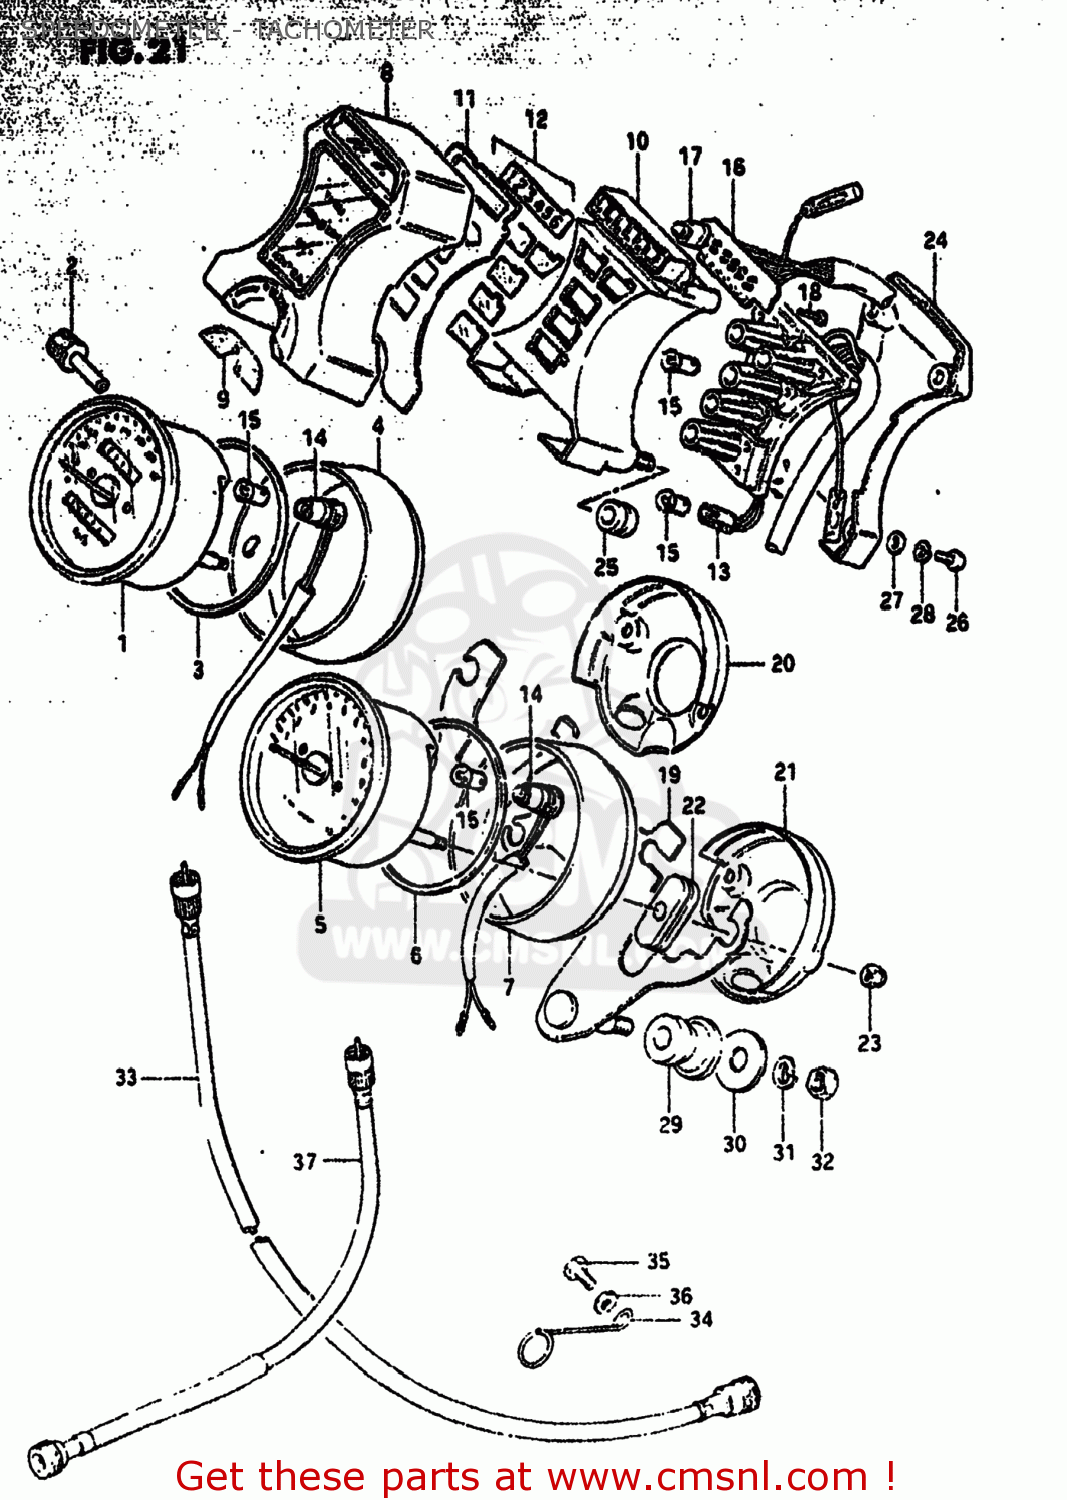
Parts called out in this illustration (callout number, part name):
1	SPEEDOMETER ASSEMBLY
2	KNOB,TRIP
3	CUSHION,SPEEDOMETER
4	COVER,SPEEDOMETER
5	TACHOMETER
6	CUSHION,SPEEDOMETER
7	COVER,TACHOMETER
8	CASE,PILOT BULB
9	PAD
10	CASE,PILOT BULB,INNER
11	CUSHION
12	LENS SET,PILOT LAMP
13	SOCKET
14	SOCKET,METER
15	BULB(12V3.4W,STANLEY,A72A)
16	SOCKET,GEAR INDICATOR
17	BULB(14V1.12W)
18	SCREW,GEAR INDICATOR
19	BRACKET,COMBINATION METER
20	COVER,SPEEDOMETER,UNDER
21	COVER,TACHOMETER,UNDER
22	CUSHION,METER
23	NUT
24	COVER,PILOT BOX,UNDER
25	CUSHION
26	SCREW
27	WASHER
28	LOCK WASHER
29	CUSHION,METER BRACKET
30	WASHER (8.5X29X1.6)
31	LOCK WASHER
32	NUT
33	CABLE ASSEMBLY,SPEEDOMETER
34	CLAMP,SPEEDOMETER CABLE
35	BOLT, UPPER
36	WASHER
37	CABLE ASSEMBLY,TACHOMETER
